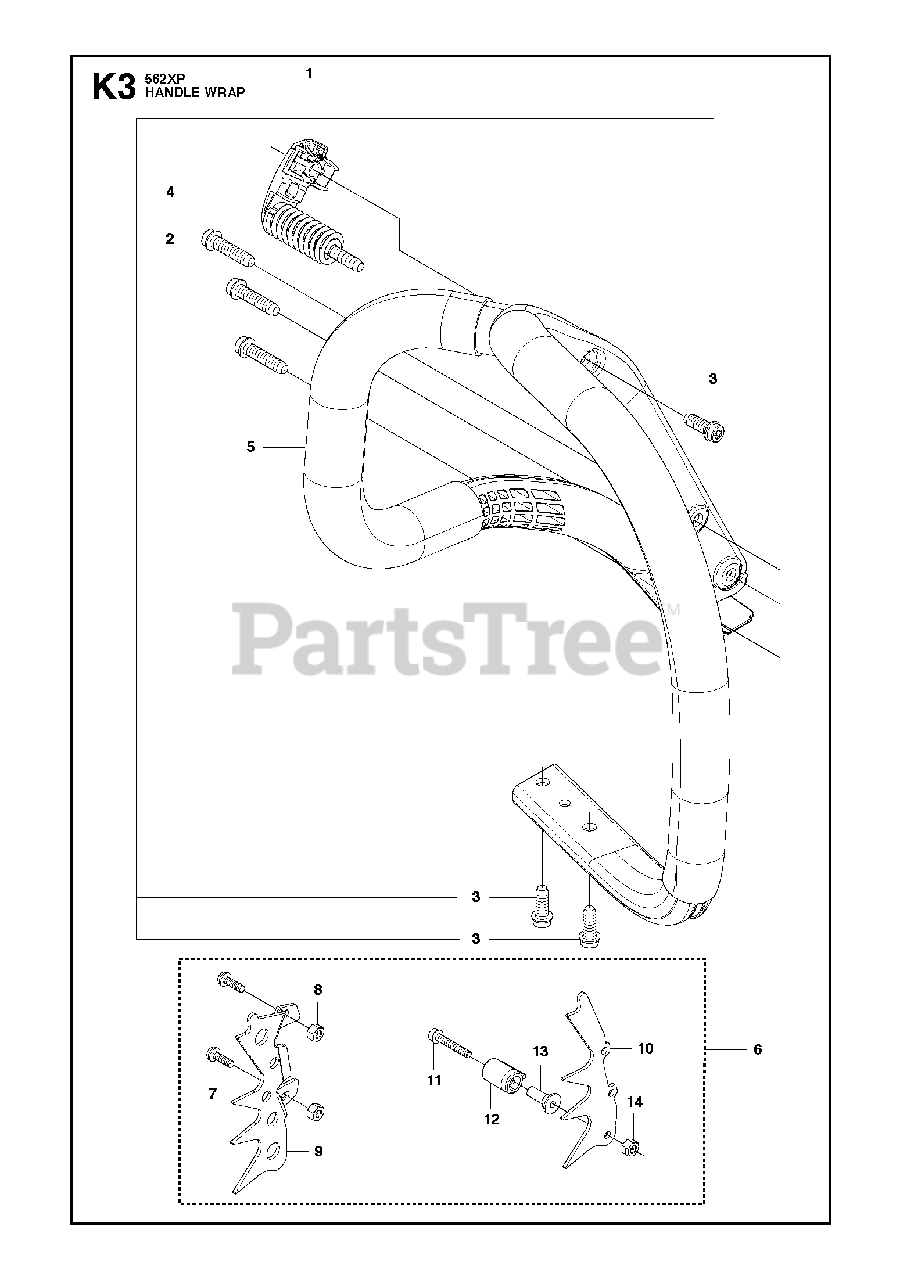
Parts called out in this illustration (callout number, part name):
1	ENCLOSED KIT
2	SCREW
3	SCREW IHSCFT
4	ANTIVIBRATION ELEMENT
5	HANDLE WRAP
7	SCREW
8	SPIKE OUTER
9	SPIKE, OUTER
10	SPIKES, INNER
11	SCREW IHSCFM
12	SPACER
13	CHAIN CATCHER
14	NUT
